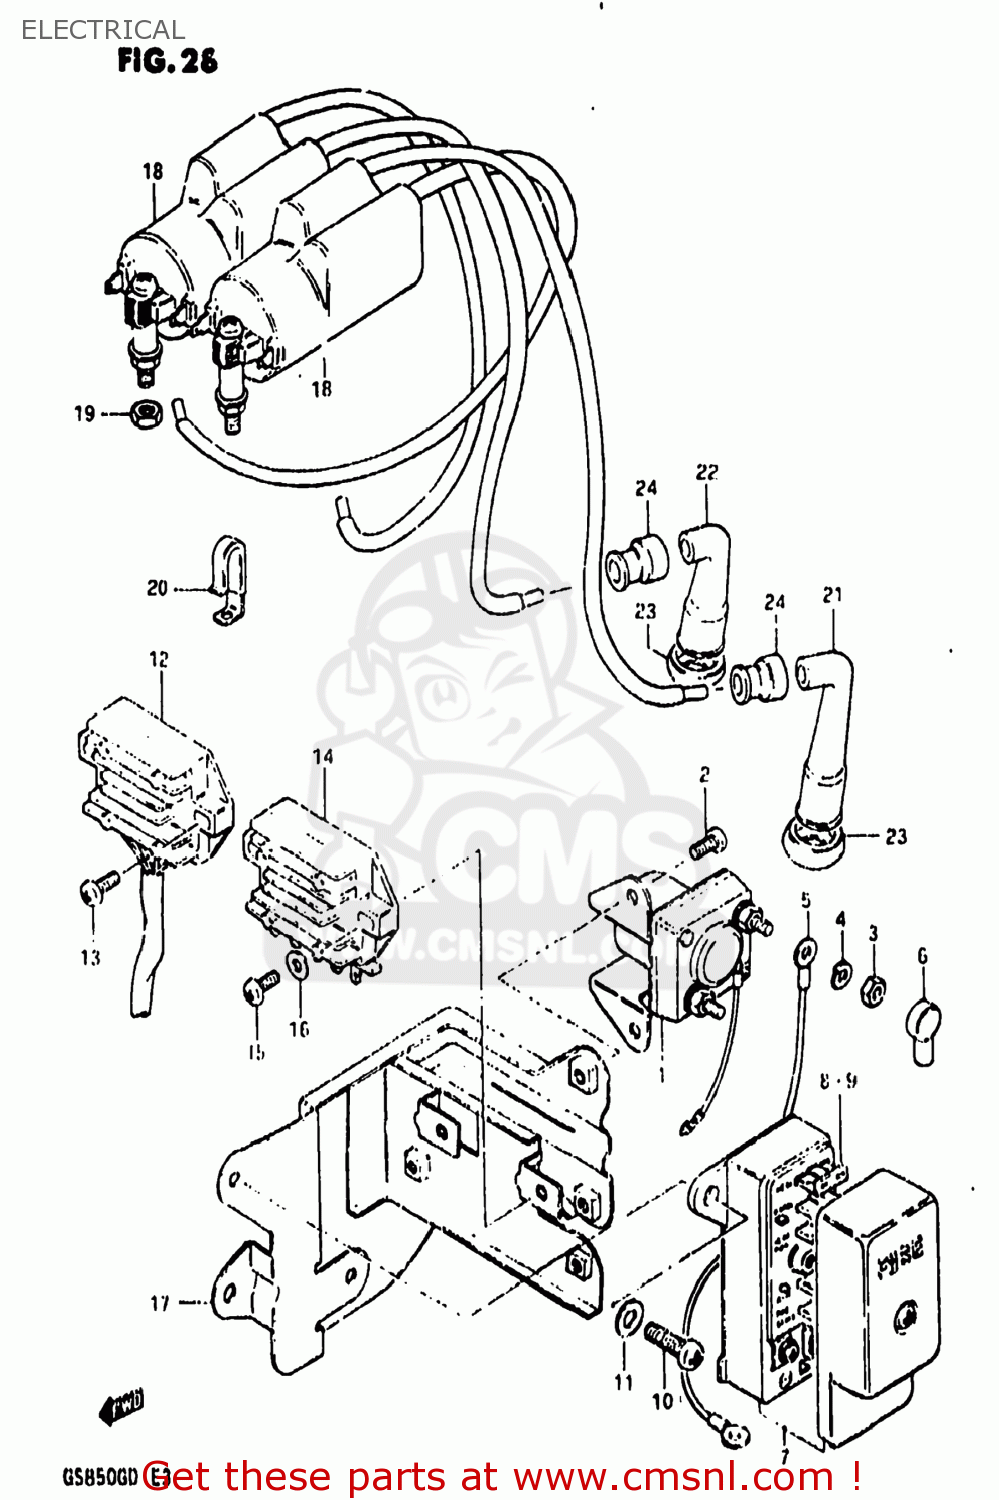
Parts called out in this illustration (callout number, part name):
1	RELAY ASSY,STARTING MOTOR
2	SCREW
3	NUT 6MM
4	LOCK WASHER
5	CABLE,STARTING MOTOR
6	CAP,STARTER RELAY
7	BOX ASSEMBLY,FUSE
8	FUSE(10A)
9	FUSE(15A)
10	SCREW 6X12
11	WASHER
12	RECTIFIER ASSEMBLY
13	SCREW 6X12
14	RECTIFIER ASSEMBLY
15	SCREW
16	WASHER
17	HOLDER COMP,ELECTRONIC PARTS
18	COIL ASSEMBLY,IGNITION
19	NUT
20	CLAMP
21	CAP ASSY,SPARK PLUG
22	CAP,SPARK PLUG
23	SEAL,SPARK PLUG
24	SEAL,SPARK PLU
